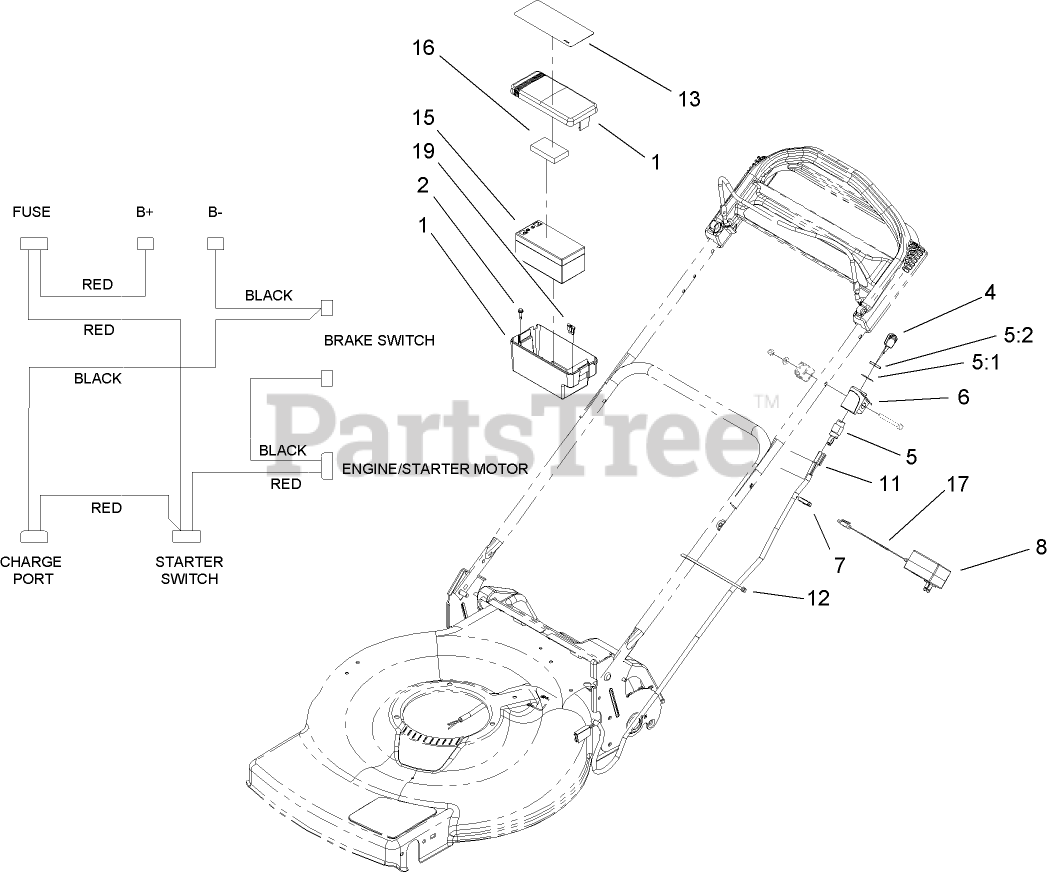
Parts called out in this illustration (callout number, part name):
1	BATTERY BOX ASM
2	SCREW-FORMING, THREAD
5	STARTER SWITCH ASM
5:1	WASHER-LOCK
5:2	NUT-HH
6	MOUNT-SWITCH
7	HARNESS-WIRE
8	CHARGER-EUROPEAN, 12V DC
11	DECAL-WARNING
12	TIE-CABLE
13	DECAL-INSTRUCTIONAL
15	BATTERY-WET
16	FOAM-BATTERY, TOP
17	ADAPTER-CHARGER
19	FUSE-40 AMP
